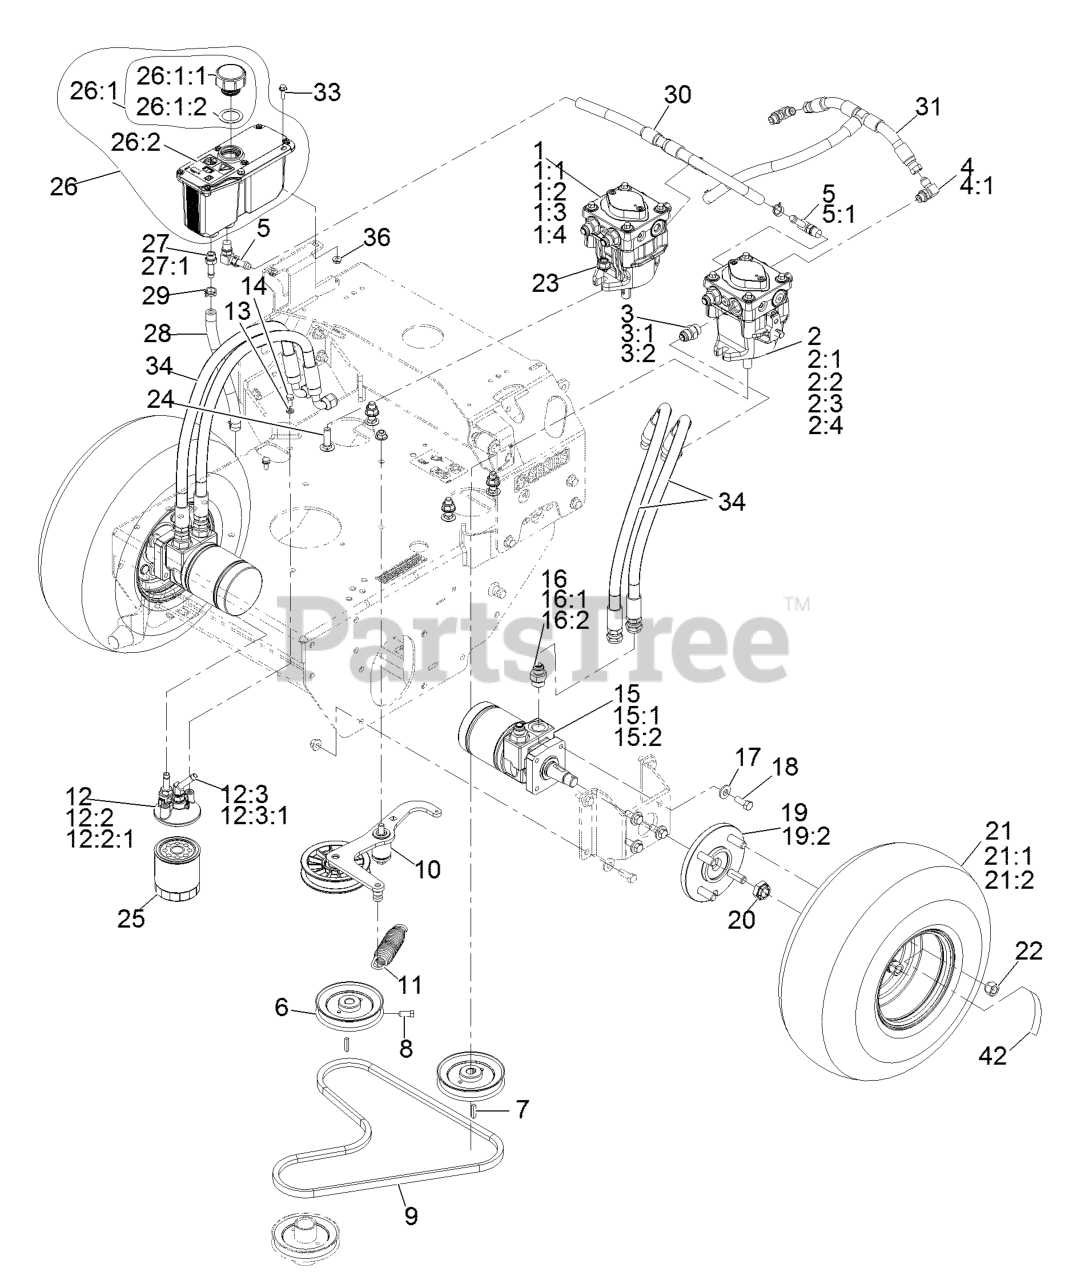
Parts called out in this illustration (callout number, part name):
1	RH HYD PUMP ASM
1:1	INPUT SHAFT KIT
1:2	BEARING-THRUST
1:3	CYLINDER BLOCK KIT
1:4	SEAL OVERHAUL KIT
2	LH HYD PUMP ASM
2:1	INPUT SHAFT KIT
2:2	BEARING-THRUST
2:3	CYLINDER BLOCK KIT
2:4	SEAL OVERHAUL KIT
3	FITTING-STRAIGHT
4	FITTING-ELBOW, 90 DEG
5	FITTING-ELBOW, 90
5:1	O-RING
6	SHEAVE ASM
8	SCREW-SET, SQH
9	BELT
10	ASM, PUMP IDLER
11	SPRING-EXTENSION
12	ASM, FILTER HEAD
12:2	ADAPTER-STRAIGHT
12:2:1	O-RING
12:3	FITTING-BARBED, 45 DEG
12:3:1	O-RING
13	WASHER-LOCK
14	SCREW-HH
15	HYD MOTOR ASM
15:1	SEAL KIT
15:2	BEARING AND SEAL KIT
16	FITTING-STRAIGHT
16:1	O-RING
17	WASHER-BELLEVILLE
18	SCREW-HH
19	WHEEL HUB ASM
19:2	STUD-WHEEL
20	NUT-LOCK
21	WHEEL AND TIRE ASM
21:1	TIRE-TURFMASTER
21:2	RIM-WHEEL
22	NUT-LUG
23	NUT-HF, NI
24	SCREW-HH
25	FILTER-25 MICRON, BI-DIRE
26:1	Reservoir-HYD
26:1:1	Cap-Reservoir, HYD
26:1:2	GASKET-CAP
26:2	DECAL-WARNING
27	ADAPTER-STRAIGHT
27:1	O-RING
28	HOSE-CHARGE
29	CLAMP-HOSE
30	HOSE-CASE DRAIN
31	HOSE-CHARGE
33	SCREW-HWH
34	HYD HOSE ASM
42	DECAL-TORQUE WHEEL LUG-HU
